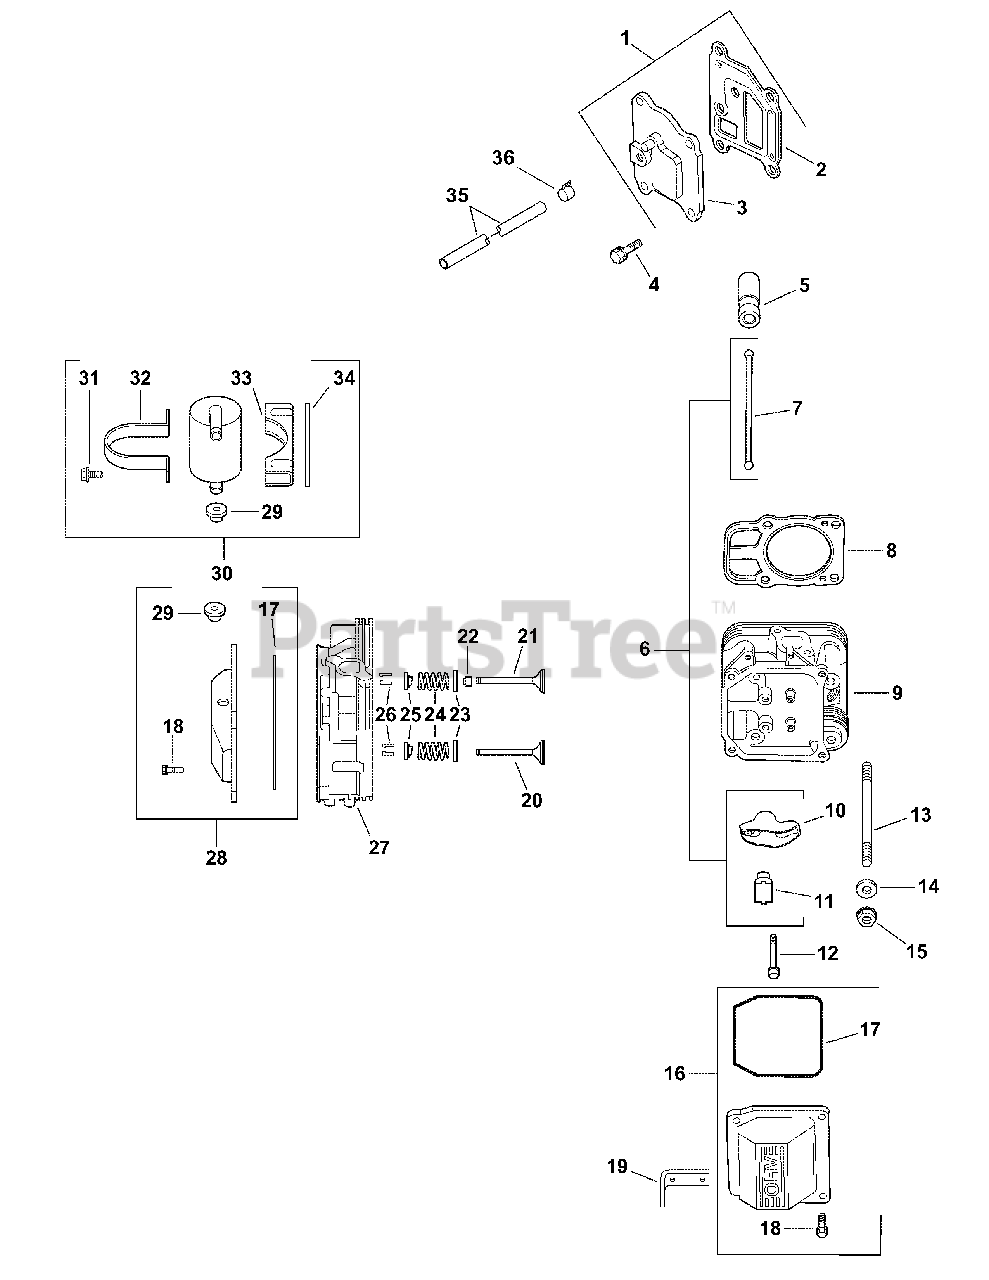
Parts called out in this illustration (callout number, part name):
1	KIT, BREATHER COVER W/GASKET
2	GASKET, BREATHER
3	COVER, BREATHER
4	SCREW, FLG THD FRM M6X1.0X20
5	KIT, HYDRAULIC VALVE LIFTER
6	KIT, VALVE TRAIN
8	KIT, CYLINDER HEAD GASKET
9	KIT, #2 CYLINDER HEAD (CV750)
11	PIVOT, ROCKER ARM
12	SCREW, FLG M6X1.0X34
13	STUD, M8X1.25, M10X1.5, 105MM
14	WASHER, FLAT 8.6 MM
15	NUT, FLG M8X1.25
16	KIT, PLAIN ROCKER COVER
17	O-RING, VALVE COVER
18	SCREW, FLG M6X1.0X30
19	STRAP, LIFTING
20	VALVE, EXHAUST (STD)
20	VALVE, EXHAUST (.25)
21	VALVE, INTAKE (STD)
21	VALVE, INTAKE (.25)
22	SEAL, VALVE STEM
23	RETAINER, SPRING
24	SPRING, VALVE
25	CAP, VALVE SPRING
26	KIT, RETAINER
27	KIT, #1 CYLINDER HEAD (CV750)
28	KIT, BREATHER ROCKER COVER
29	GROMMET, RUBBER
30	KIT, BREATHER SEPARATOR
31	SCREW, FLG THD FRM M5X0.8X16
32	STRAP, BREATHER
33	BRACKET, BREATHER SEPARATOR
35	HOSE, BREATHER (CV750)
36	CLAMP, HOSE
